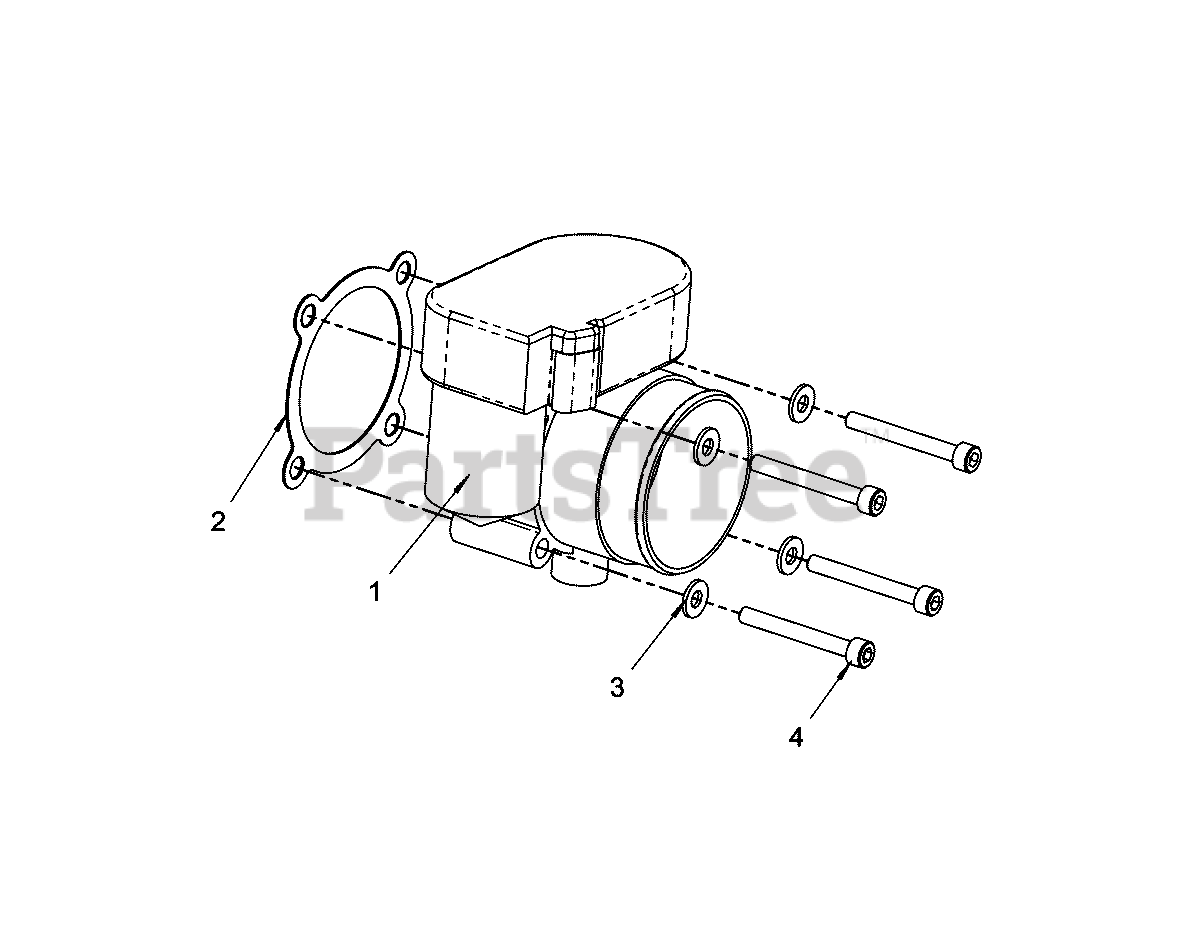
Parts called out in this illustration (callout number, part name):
1	THROTTLE BODY
2	GASKET
3	* WASHER
4	* BOLT
